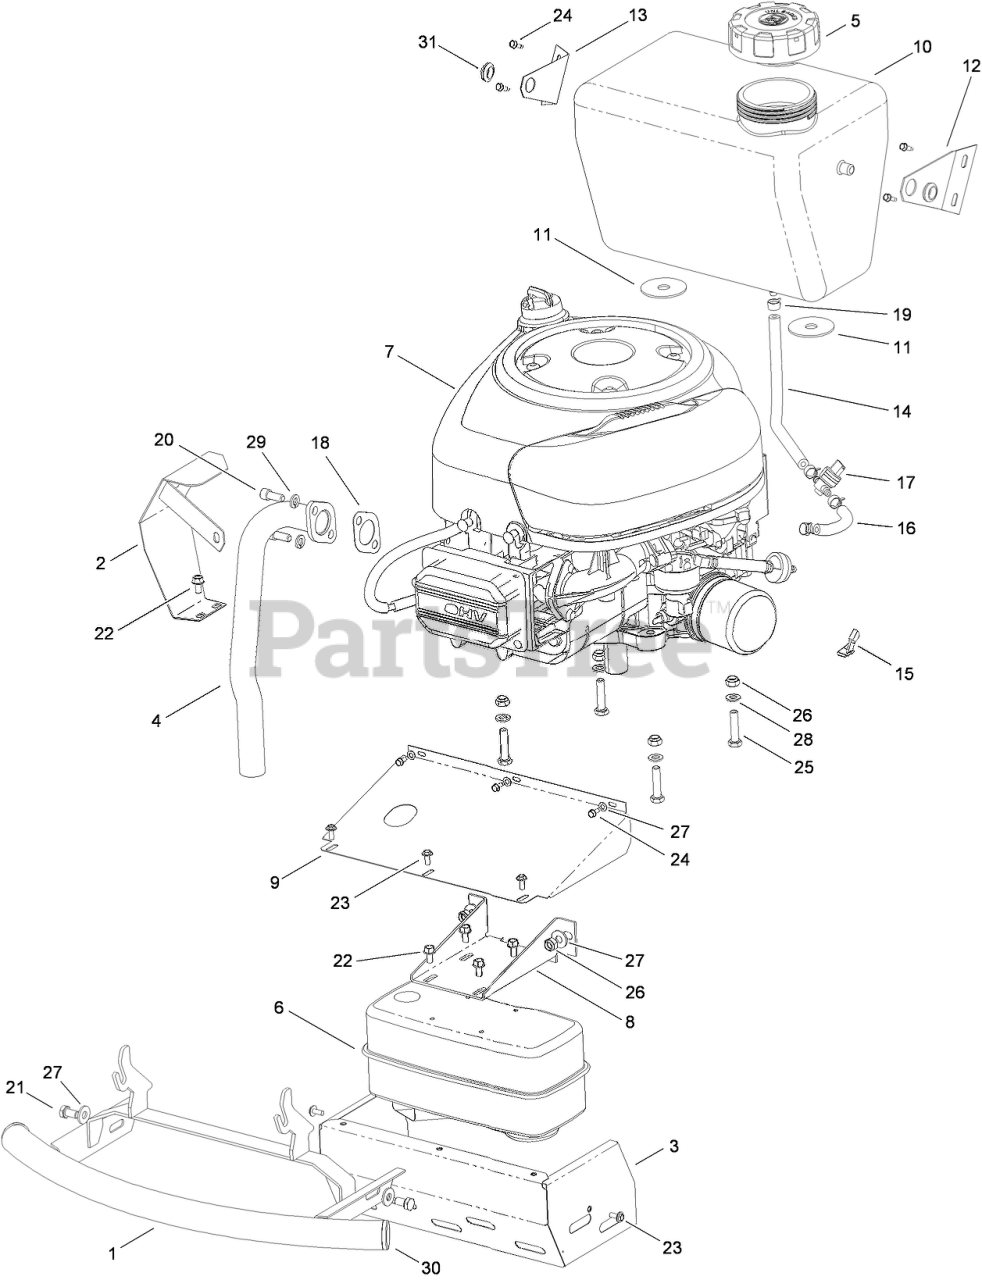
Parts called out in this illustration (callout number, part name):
1	BUMPER
2	SHIELD-EXHAUST TUBE
3	SHIELD-MUFFLER
4	TUBE-EXHAUST
5	CAP-FUEL
6	MUFFLER
8	BRACKET-MUFFLER MOUNT
9	COVER-TOP
10	TANK-FUEL
11	WASHER-RUBBER
12	BRACKET-FUEL TANK, LEFT
13	BRACKET-FUEL TANK, RIGHT
14	HOSE-FUEL
15	REDUCER-THROTTLE, RPM
16	LINE-FUEL
17	VALVE-TANK, FUEL
18	GASKET
19	CLAMP-LINE, FUEL
20	SCREW-HH
21	SCREW-HH
22	SCREW-HH
24	SCREW-TAP
25	SCREW
26	NUT-LOCK, NI
27	WASHER-PLAIN
28	WASHER-PLAIN
29	WASHER-SPRING
30	CAP-BUMPER
31	BUSHING
